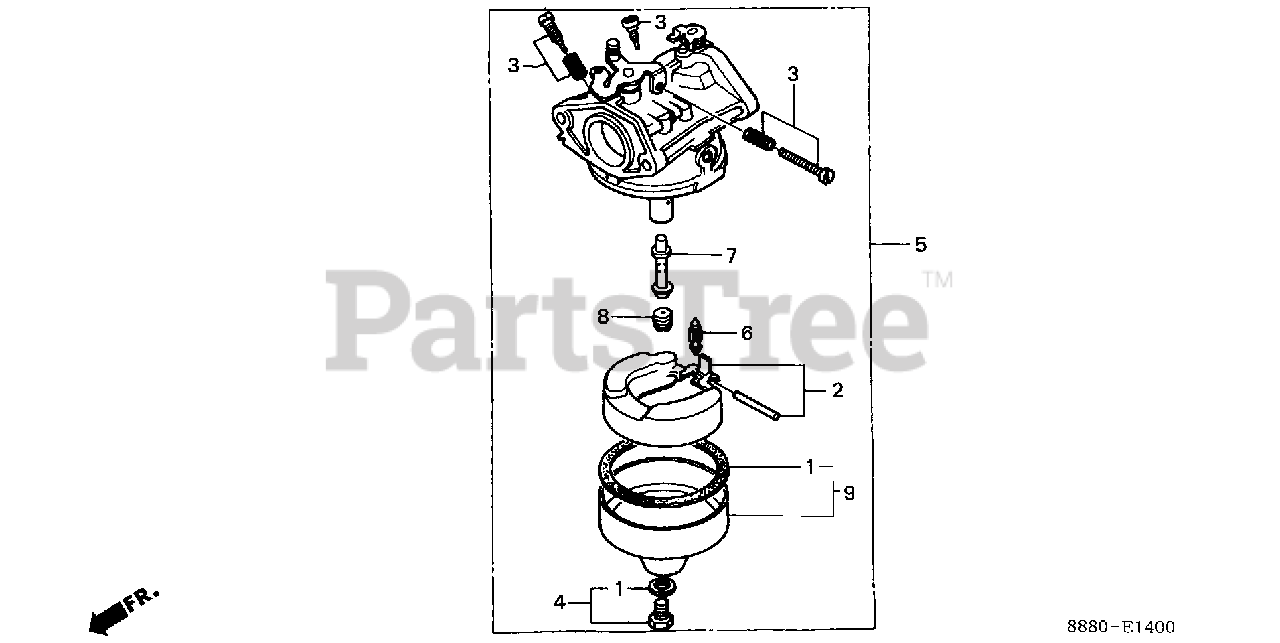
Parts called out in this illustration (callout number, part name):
1	GASKET SET (CARBURETOR NO.)
3	SCREW SET A
3	SCREW SET A (CARBURETOR NO.)
3	SCREW SET A (CARBURETOR NO.) (NOT AVAILABLE)
4	SCREW SET
5	CARBURETOR ASSY. (BB27A E)
6	VALVE, FLOAT
7	NOZZLE, MAIN
8	JET, MAIN (#58)
8	JET, MAIN (#60)
8	JET, MAIN (#62)
8	JET, MAIN (#65)
9	CHAMBER SET, FLOAT
